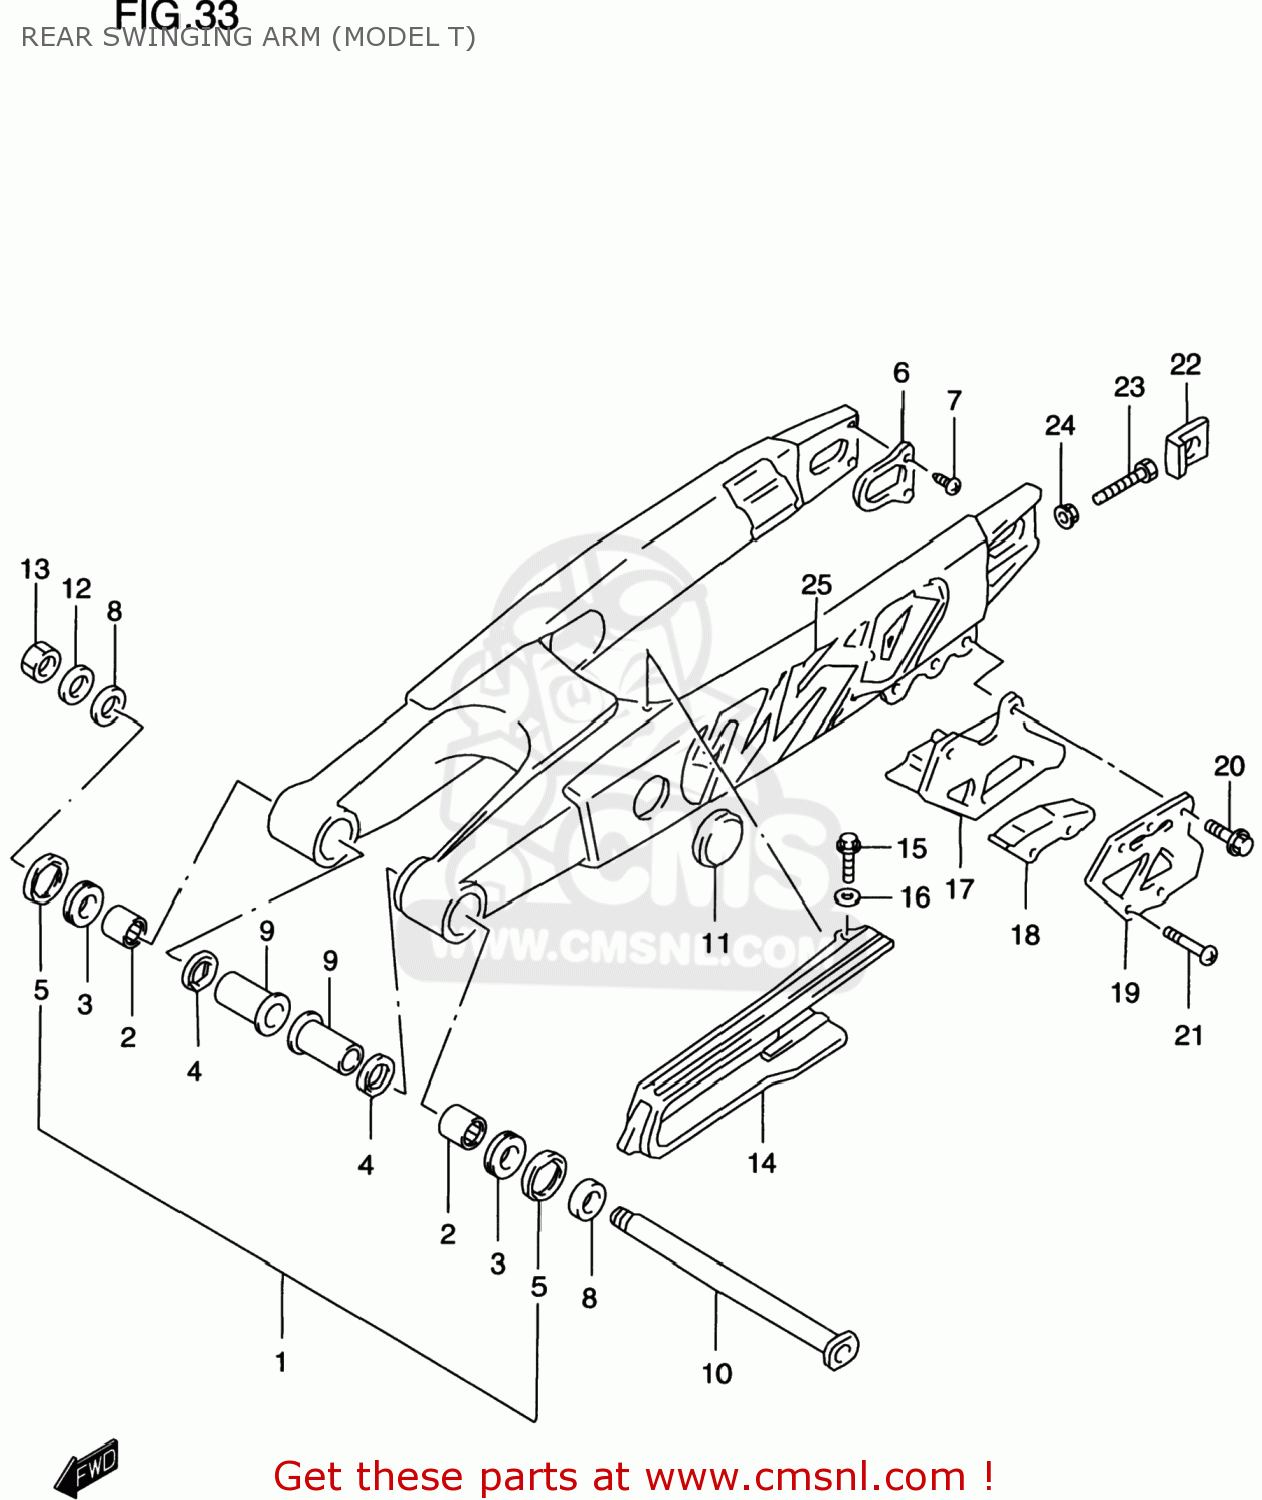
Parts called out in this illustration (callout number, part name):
1	SWING ARM ASSEMBLY,REAR
2	BEARING(22X29X30)
3	BEARING(22X35X2)
4	SEAL,OIL(22X29X4)
5	SEAL,RR SWGARM PIVOT OUTER
6	PLATE,SWING ARM,REAR
7	SCREW(5X8)
8	SPACER,RR SWGARM PIVOT OUTER
9	SPACER,SWGARM PIVOT INNER
10	SHAFT,RR SWINGINGARM PIVOT
11	CAP(OD:45)
12	WASHER, FIXED DRIVE FACE
13	NUT
14	BUFFER,CHAIN TOUCH DEFENSE
15	BOLT
16	WASHER
17	GUIDE,CHAIN
18	DEFENSE,CHAIN GUIDE
19	PLATE,CHAIN GUIDE OUTER
20	SCREW
21	SCREW(6X40)
22	WASHER,CHAIN ADJUSTER
23	BOLT(8X50)
24	NUT
25	EMBLEM,SWING ARM (250)
